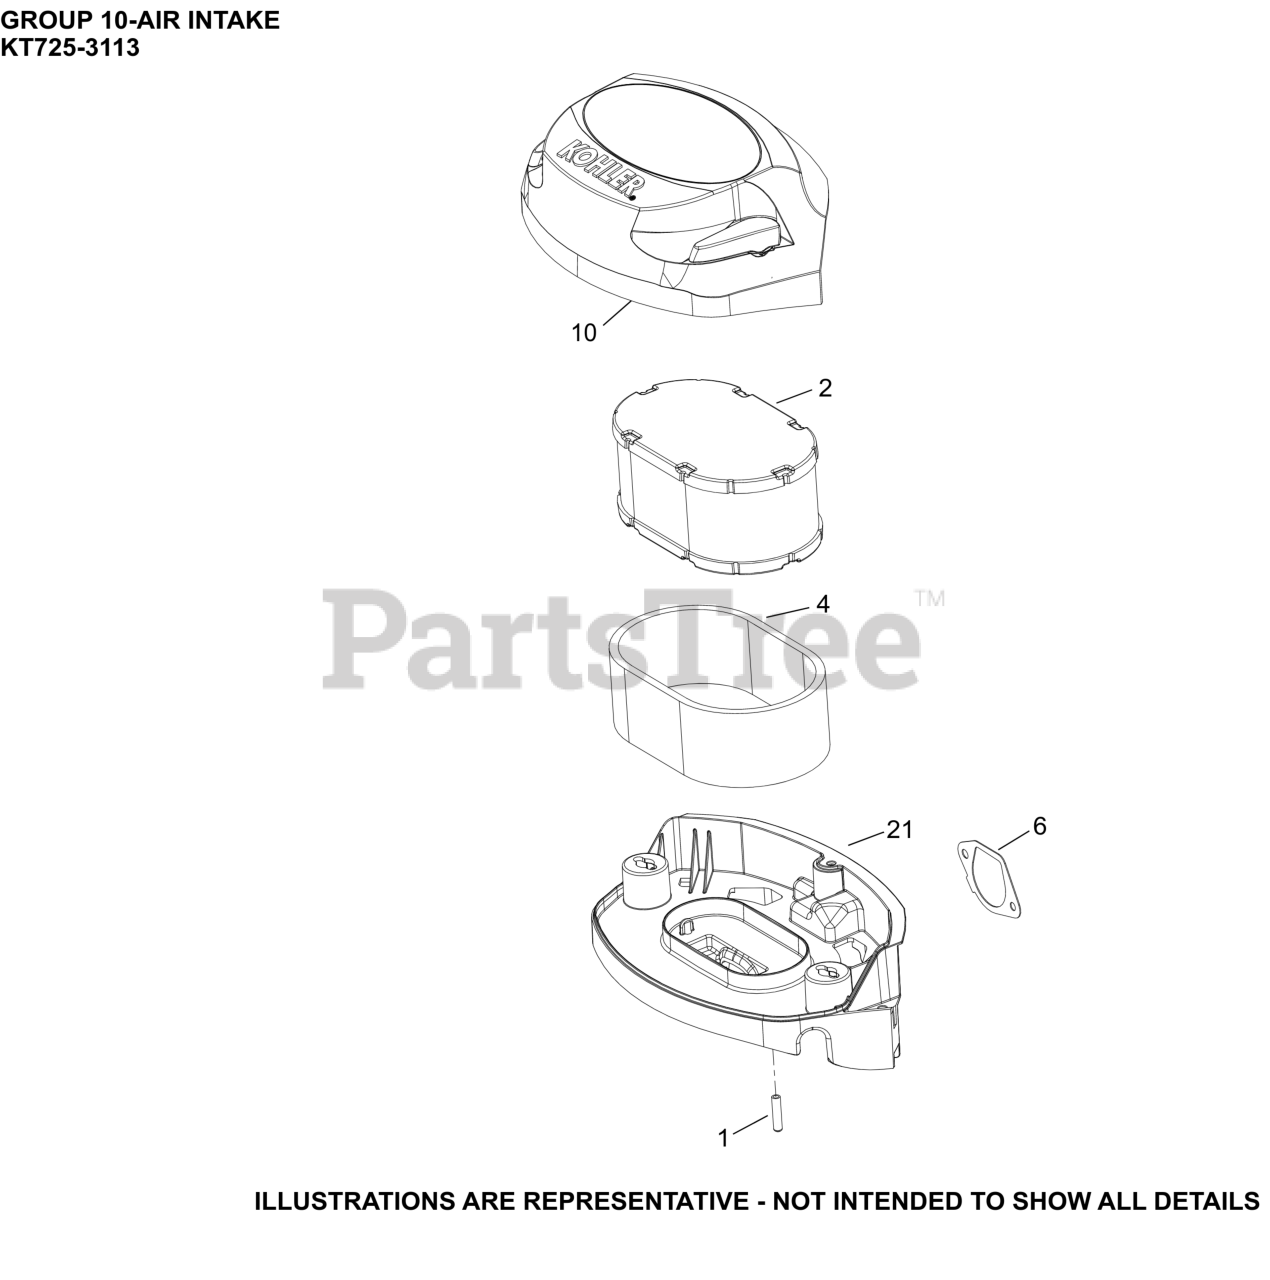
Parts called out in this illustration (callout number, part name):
1	CAP, MASKING
2	ELEMENT, AIR FILTER
4	ELEMENT, PRE-CLEANER
6	GASKET, AIR CLEANER BASE
10	COVER ASSY, AIR CLEANER
21	BASE ASSEMBLY, AIR CLEANER
